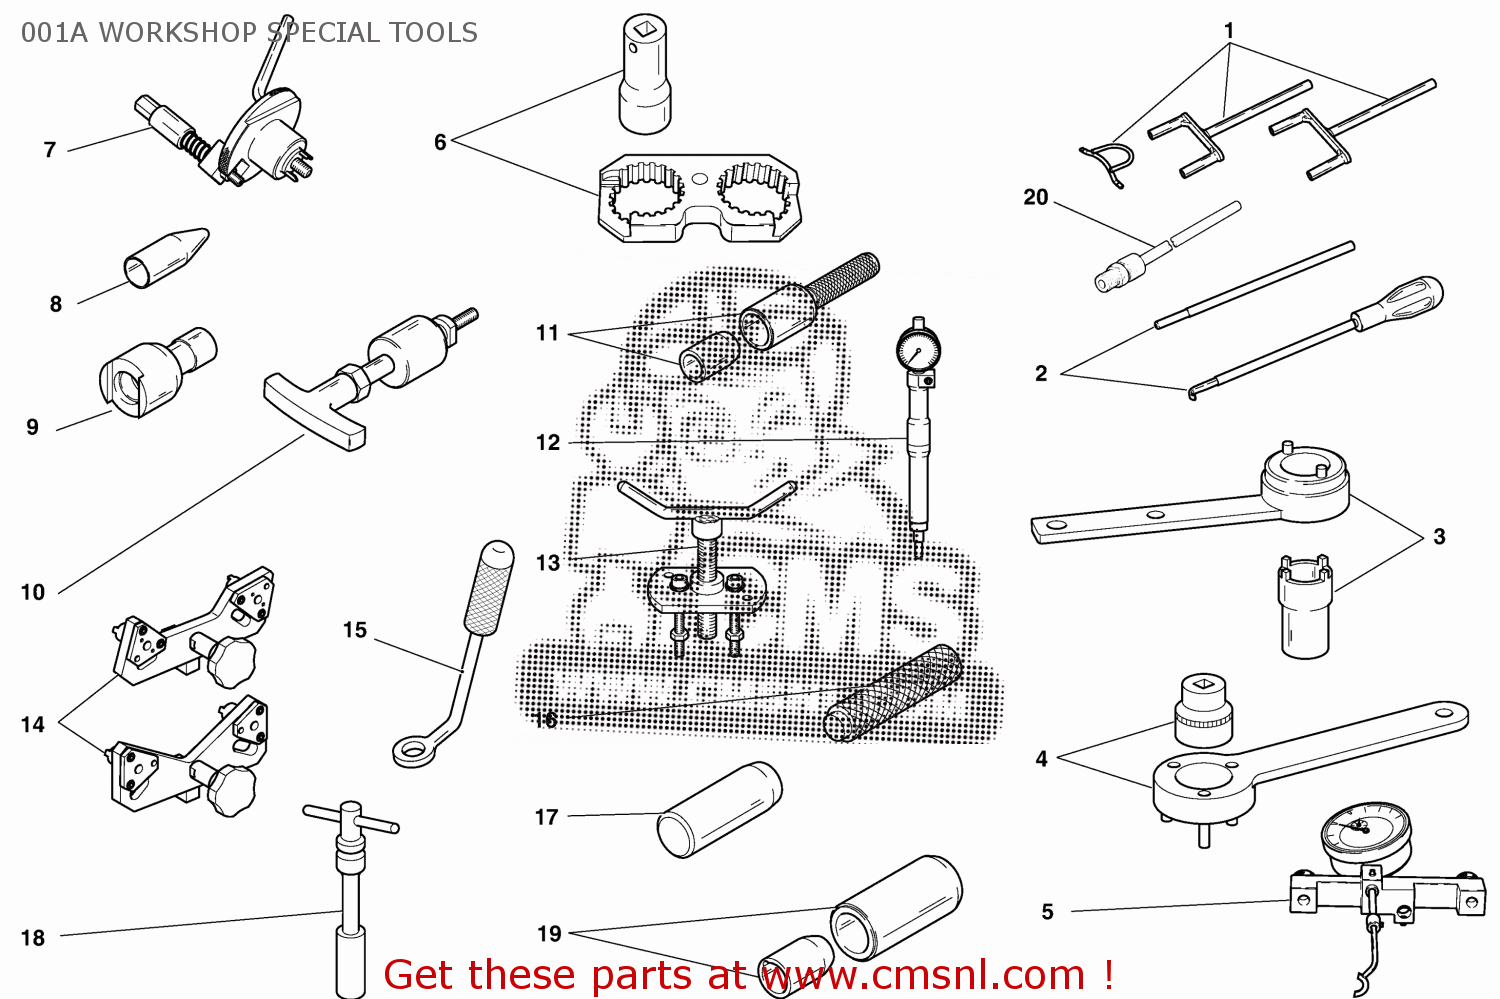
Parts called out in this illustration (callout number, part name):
1	CLOSING ROCKER PRE-LOAD KIT
2	ROCKER SPRING PRE-LOAD COMPOUND KIT
3	DRIVING ROLLER TIGHTENING TOOL
4	PRIMARY DRIVE GEAR TIGHTENING TOOL
5	VALVE LIFT GAUGE
6	REACTION TOOL BELT ROLLER TIGHTENING
7	CRANKSHAFT RESET TOOL
8	TOOL TO FIT O-RINGS ONTO STUD BOLTS
9	WRENCH TO TIGHTEN TENSIONING BOLTS
10	ROCKER PIN EXTRACTOR
11	SEAL RING DRIVING TOOL
12	T.D.C. CONTROL GAUGE
13	DRIVE ROLLER PULLER
14	BELT ROLLER TIMING TOOL
15	HALF-RINGS MOUNTING PUNCH TOOL
16	DRIFT TO DRIVE RETAINERS ONTO SHAFTS
17	TOOL TO FIT CAM BLANKING CAPS
18	SPARK PLUG WRENCH
19	TOOL TO FIT OIL SEAL
20	CONNECTOR FOR EXHAUST GAS TAKE-UP POINT
